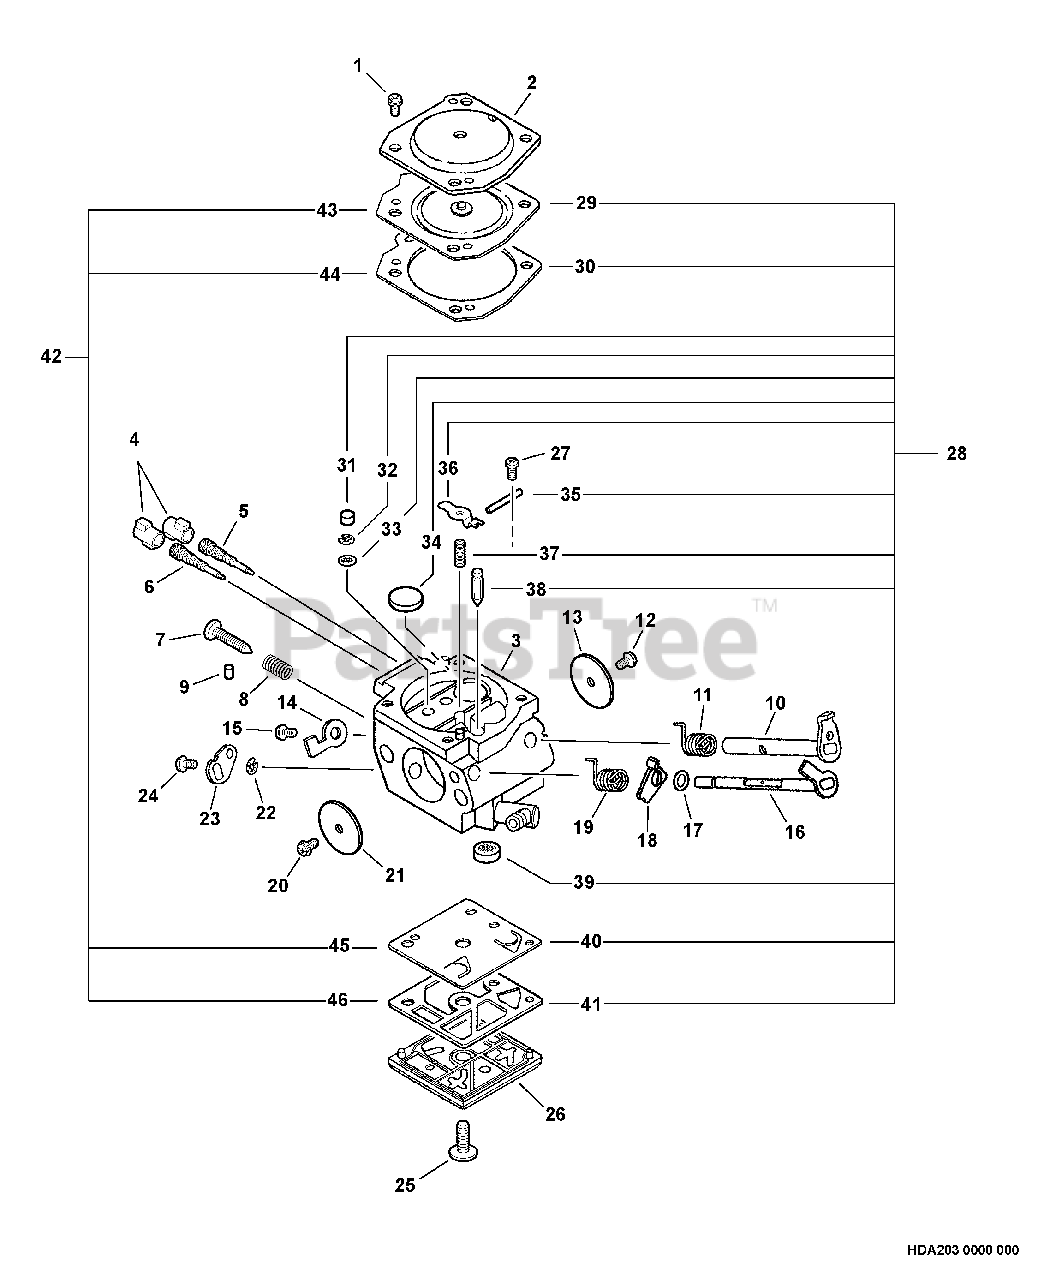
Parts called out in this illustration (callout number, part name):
2	COVER, METERING DIAPHRAGM
3	BODY, CARBURETOR
4	CAP, LIMITER
5	NEEDLE, MIXTURE
6	NEEDLE, HIGH SPEED
7	SCREW, IDLE ADJUST
9	PLUG, FRICTION
10	SHAFT ASSY, THROTTLE
11	SPRING, THROTTLE RETURN
13	VALVE, THROTTLE
14	STOP, THROTTLE
16	SHAFT ASSY, CHOKE
18	LEVER, FAST IDLE
19	SPRING, CHOKE RETURN
21	VALVE, CHOKE
23	LEVER, CHOKE
26	COVER, FUEL PUMP
27	SCREW, METERING LEVER PIN
28	REPAIR KIT, CARBURETOR
29	DIAPHRAGM, METERING
30	GASKET, DIAPHRAGM
31	PLUG, CUP
32	RING, RETAINING
33	STRAINER
34	PLUG, WELCH
35	PIN, METERING LEVER
36	LEVER, METERING
37	SPRING, METERING LEVER
38	VALVE, INLET NEEDLE
39	STRAINER
40	DIAPHRAGM, PUMP
41	GASKET, PUMP
42	GASKET / DIAPHRAGM KIT
43	DIAPHRAGM, METERING
44	GASKET, DIAPHRAGM
45	DIAPHRAGM, PUMP
46	GASKET, PUMP
